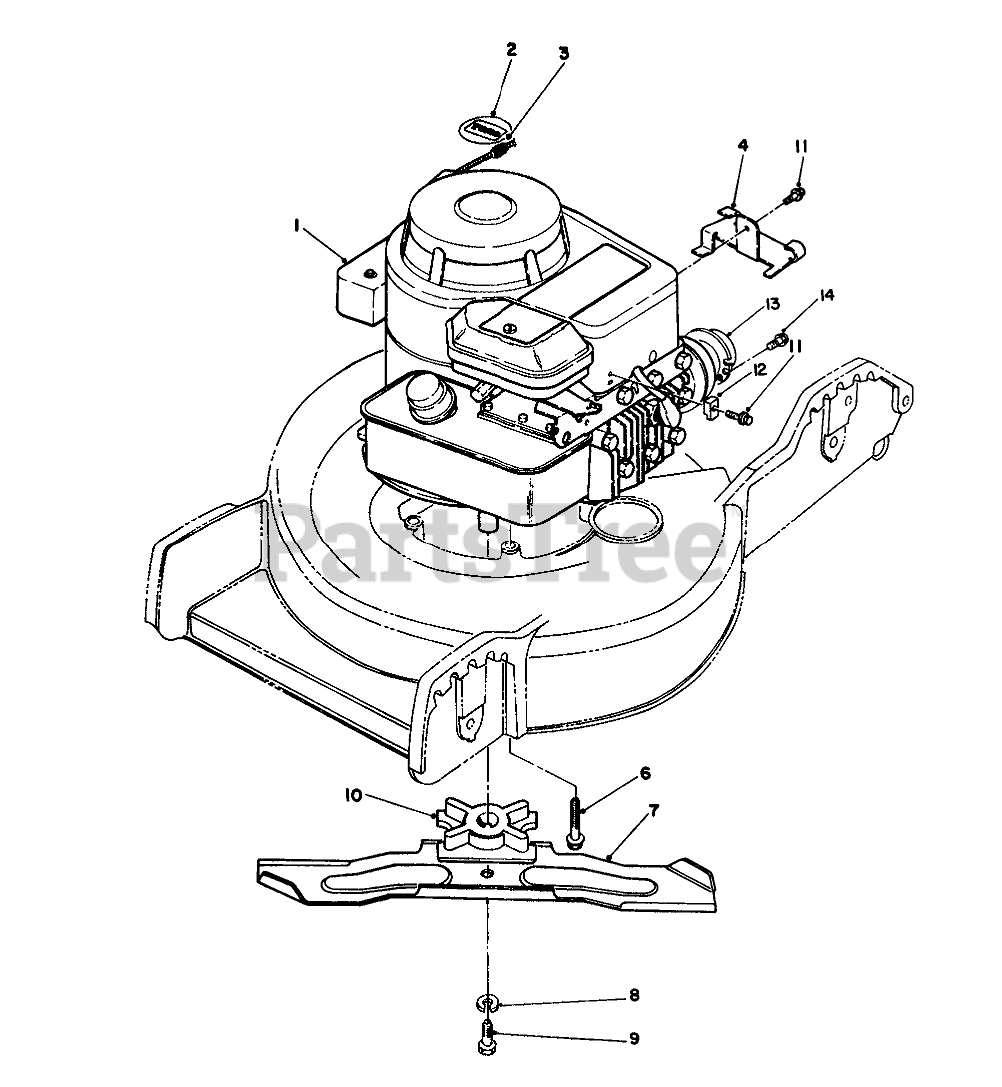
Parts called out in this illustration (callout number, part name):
2	Decal-Toro
3	STOP-ROPE
4	CABLE BRACKET
6	3/8-16X2 TAPTITE HEX HD
7	Blade-18"
8	WASHER-LOCK
9	SCREW-HH
10	BLADE RETAINER
11	CLAMP SCREW F/W ENGINE
12	CASING CLAMP F/W ENGINE
13	MUFFLER DEFLECTOR F/W
14	SCREW W/ENGINE
